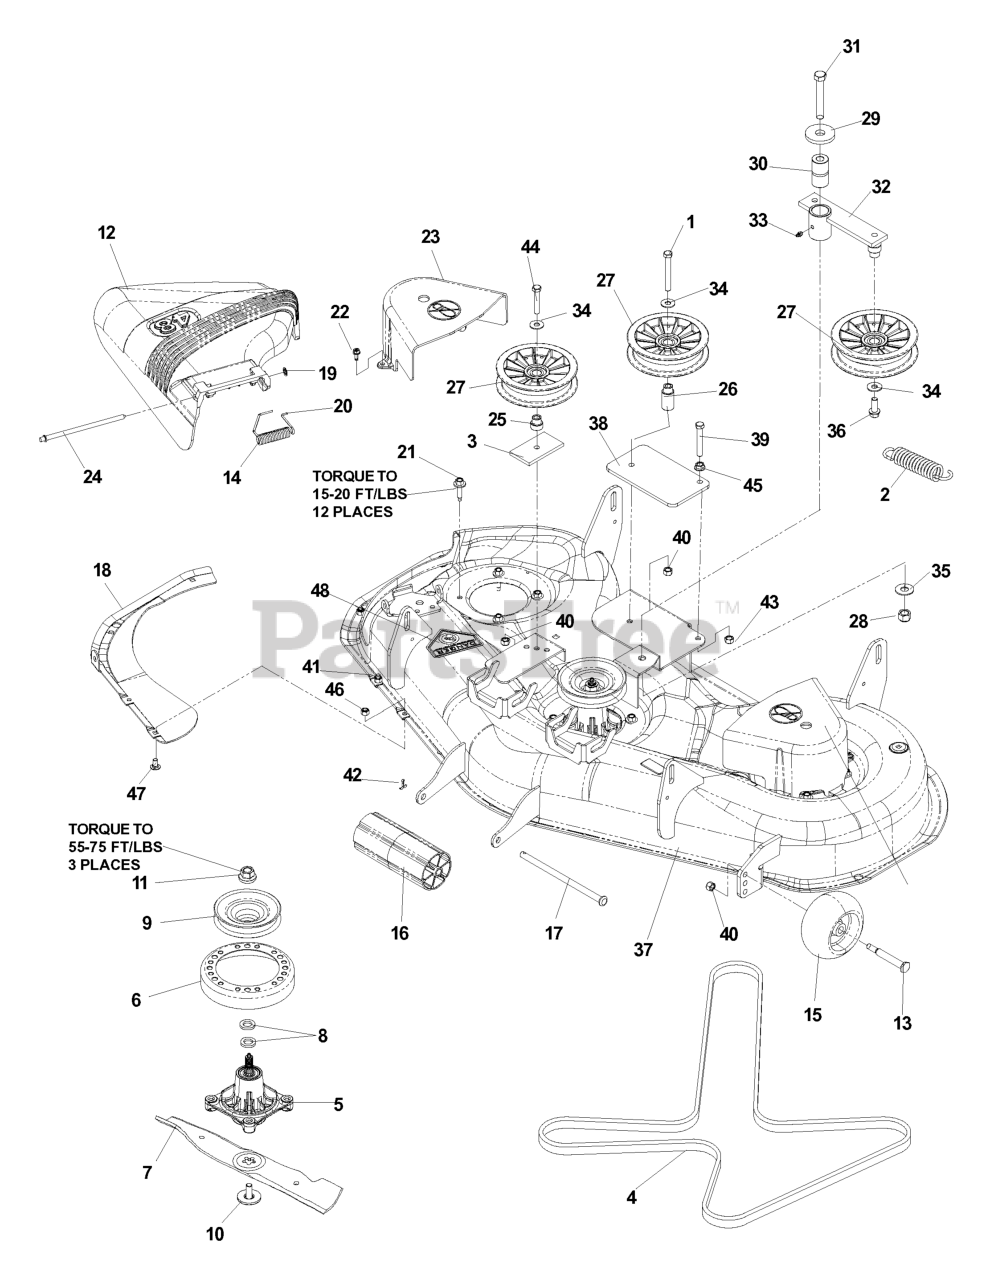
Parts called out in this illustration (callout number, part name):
1	HCS 3/8C X 3
3	SUPPORT PLATE
4	BELT, DECK
5	MANDREL ASM
6	STRIPPER-ROUND-UNIVERSAL
7	48" HI-LIFT BLADE
8	WASHER-SPACER
9	PULLEY.DRIVEN.DECK.48'
10	BOLT 7/16 ASM BLADE
11	LOCKNUT - 9/16
12	DEFLECTOR.ASM.BLACK.48"
13	BOLT, SHOULDER
14	TORSION SPRING
15	WHEEL GAGE DONUT
16	NOSE ROLLER 48"
17	NOSE ROLLER ROD
18	VORTEX MOWER BAFFLE
19	PUSH NUT
20	CAP-SLEEVE
21	WASHER HEAD SCREW
22	SCREW- 1/4-20 X 5/8
23	BELT SHIELD
24	ROD.HINGE
25	IDLER BUSHING
26	IDLER BUSHING
27	IDLER
28	NUT 1/2-13 HEX NYLOC ZD
29	WASHER, SUPPORT
30	PIVOT BUSHING
31	HCS 1/2C X 3 1/4
33	ZERK
34	WASHER 3/8 FLAT
35	WASHER 1/2 FLAT
36	4CS 3/8C X 1 SERRATED HEAD
37	DECK W/DECALS 48 WSL
38	SUPPORT PLATE, BLACK
39	HCS 3/8C X 2.5" GRADE 8
40	NUT 3/8-16 NYLOC
41	SCREW 5/16C X 1 HEX CAP
42	RP_COTTER PIN 1/8 X 3/4
43	NUT 3/8C CENTERBLOCK
44	HCS 3/8C X 2
45	NUT 3/8C WHIZ
46	NUT 5/16 NYLOC
47	CARRIAGE BOLT 5/16C X 5/8"
48	DECAL, CPSC
